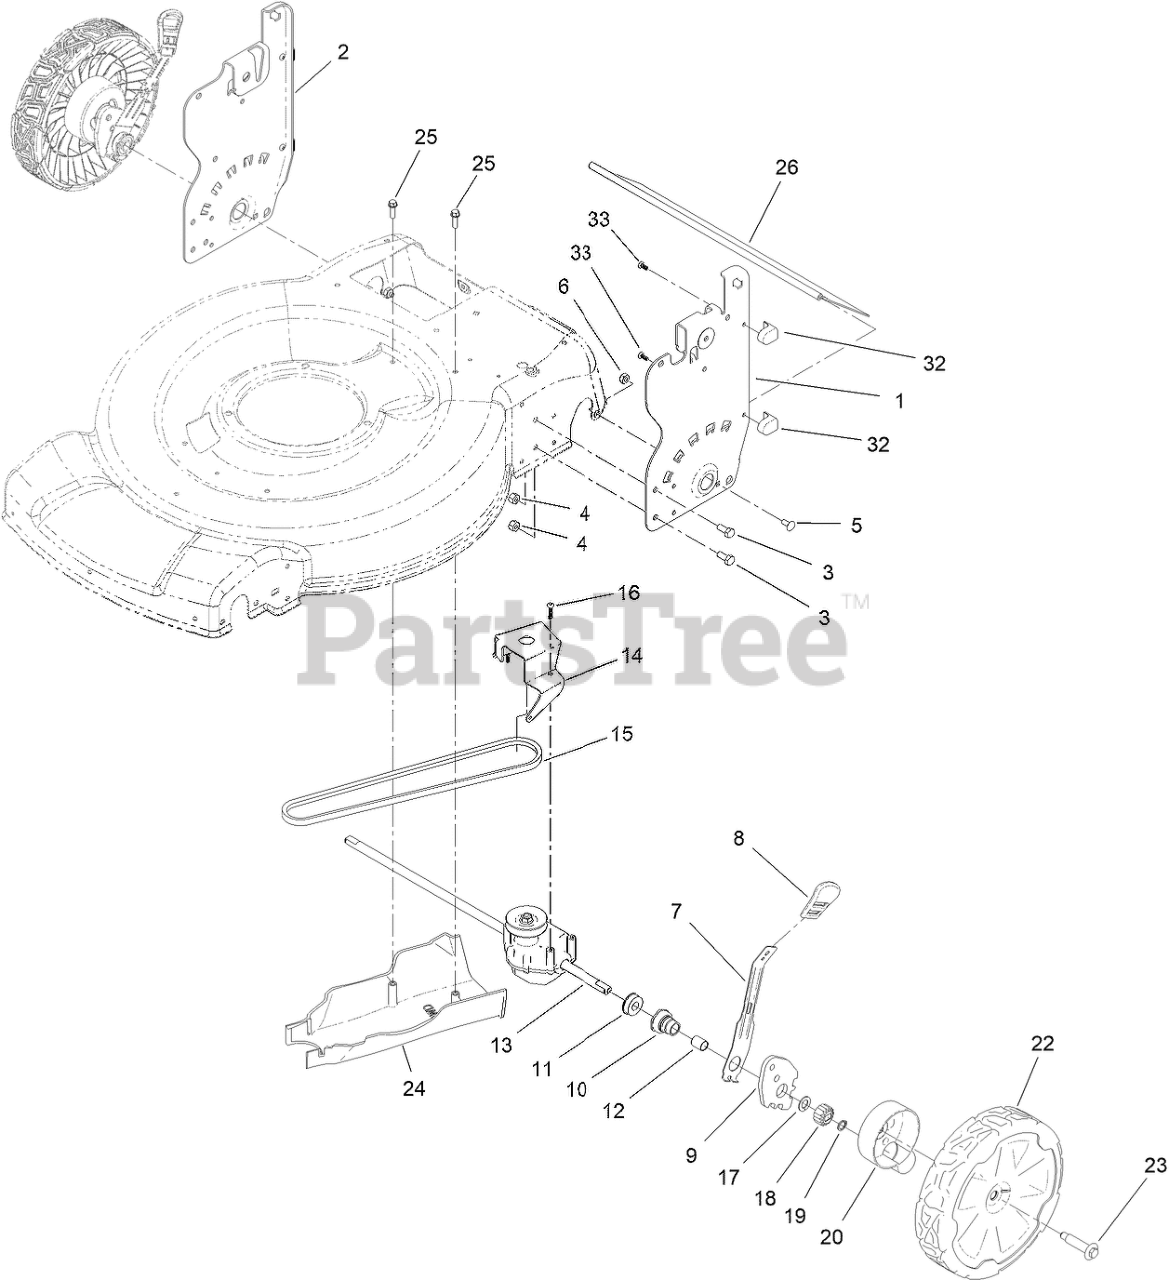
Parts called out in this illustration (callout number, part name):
1	PLATE-HOC, LH (2 HOLE)
2	PLATE-HOC, RH (2 HOLE)
3	SCREW-HH
4	NUT-LOCK, NI
5	SCREW-CARR
6	NUT-LOCK, NI
7	ARM-SPRING
8	KNOB-HOC
9	ARM-PIVOT, REAR
10	RETAINER-BUSHING, HOC
11	BEARING-BALL
12	BUSHING-SLEEVE
13	TRANSMISSION-RWD
14	BRACKET-TRANSMISSION
15	V-BELT
16	SCREW-PLASTITE
17	WASHER-THRUST
18	GEAR-PINION, 15T
19	RING-RETAINING
20	ASM-COVER, GEAR (DK GRAY)
22	ASM-9.65" WHEEL, GEARED
23	WHEEL BOLT
24	COVER-BELT, RWD
25	SCREW-HWH
26	SHIELD-TRAILING
32	PAD-SMART STOW
33	SCREW-PLASTITE
